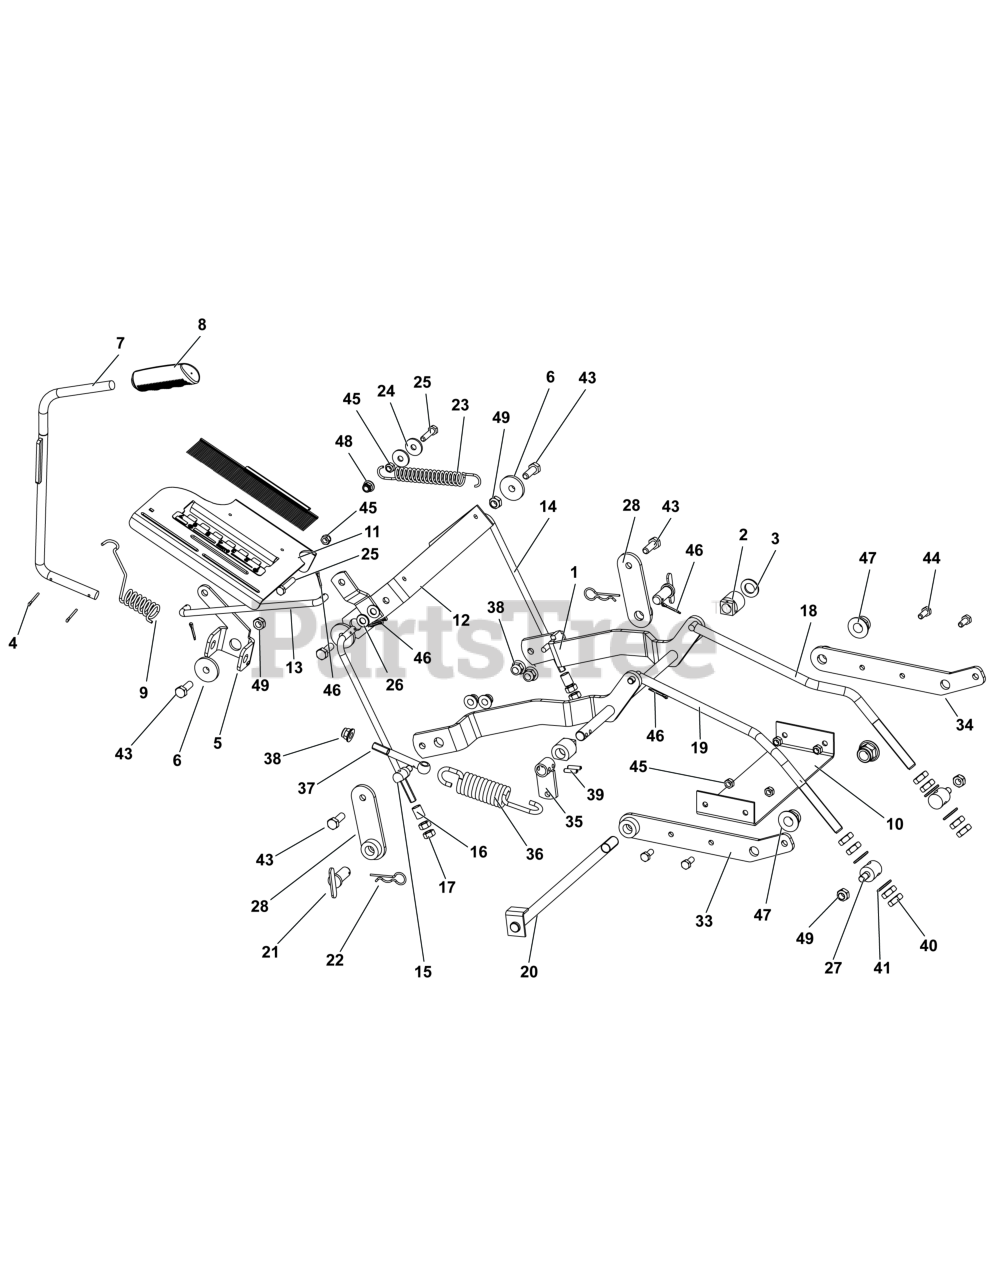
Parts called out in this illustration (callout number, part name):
8	GRIP, Handle
11	BRACKET, Lifting
37	EYE BOLT
